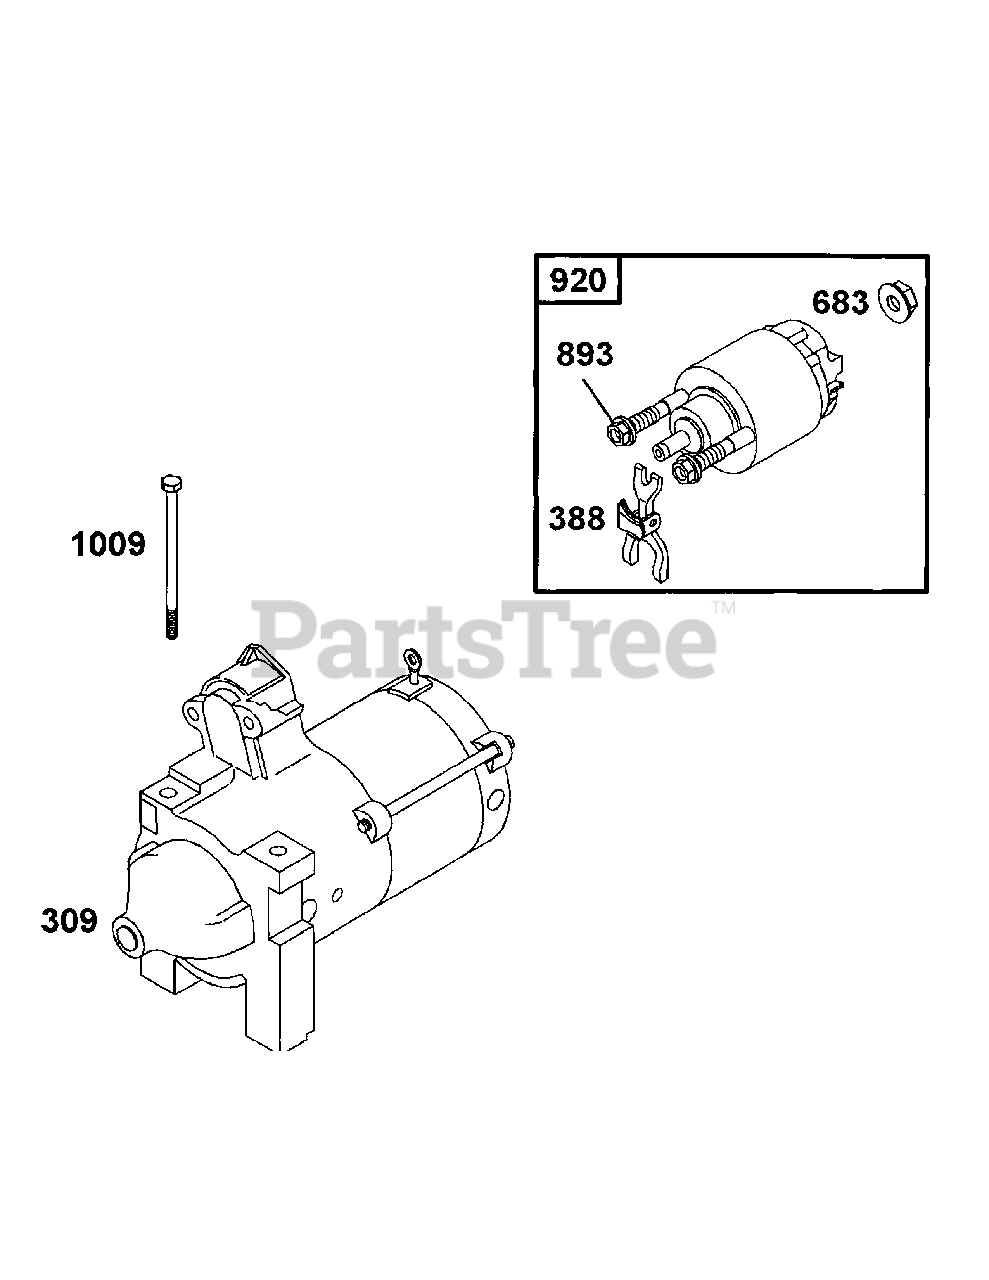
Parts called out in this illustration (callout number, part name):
309	Motor-Starter (Steel Pinion)
388	Lever-Pinion Drive
683	Nut (Starter Solenoid)
893	Nut (Starter Solenoid)
920	Solenoid-Starter
920	Solenoid-Starter (Starter Motor)
1009	Screw (Starter Motor)
